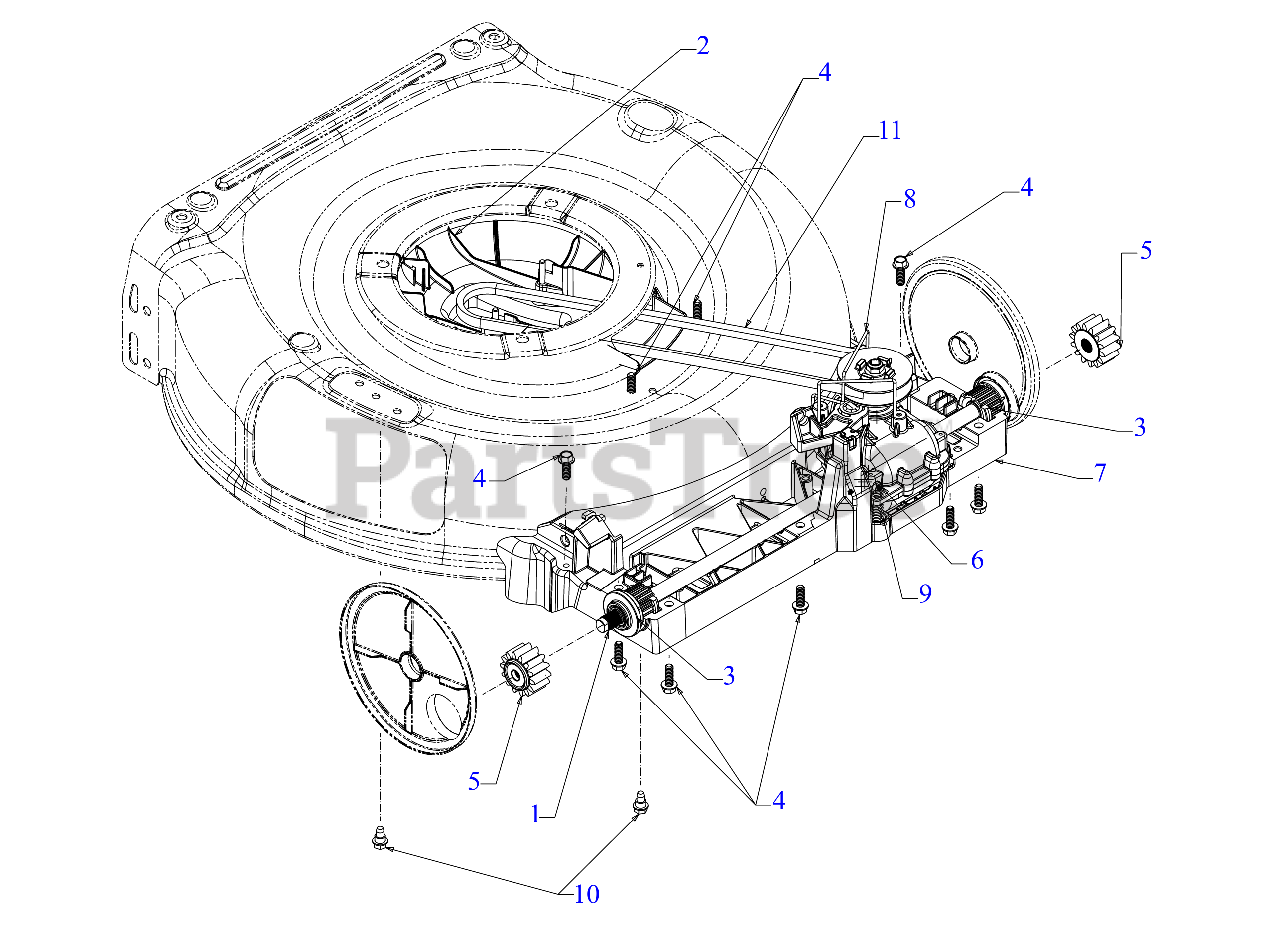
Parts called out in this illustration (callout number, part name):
1	TRANSMISSION ASSEMBLY
2	ENGINE BAFFLE ASSEMBLY
3	BEARING ASSEMBLY
4	SCREW 1/4-15 x .750
5	SPUR GEAR (14T) (RH)
6	SPRING COMPRESSION
7	LOWER TRAY
8	TRANSMISSION WIRE
9	COMPRESSION SPRING
10	SHOULDER SCREW 1/4-20 x .50
11	V-BELT 3L x 33.68
11	Genuine Factory Parts TRANSMISSION BELT
